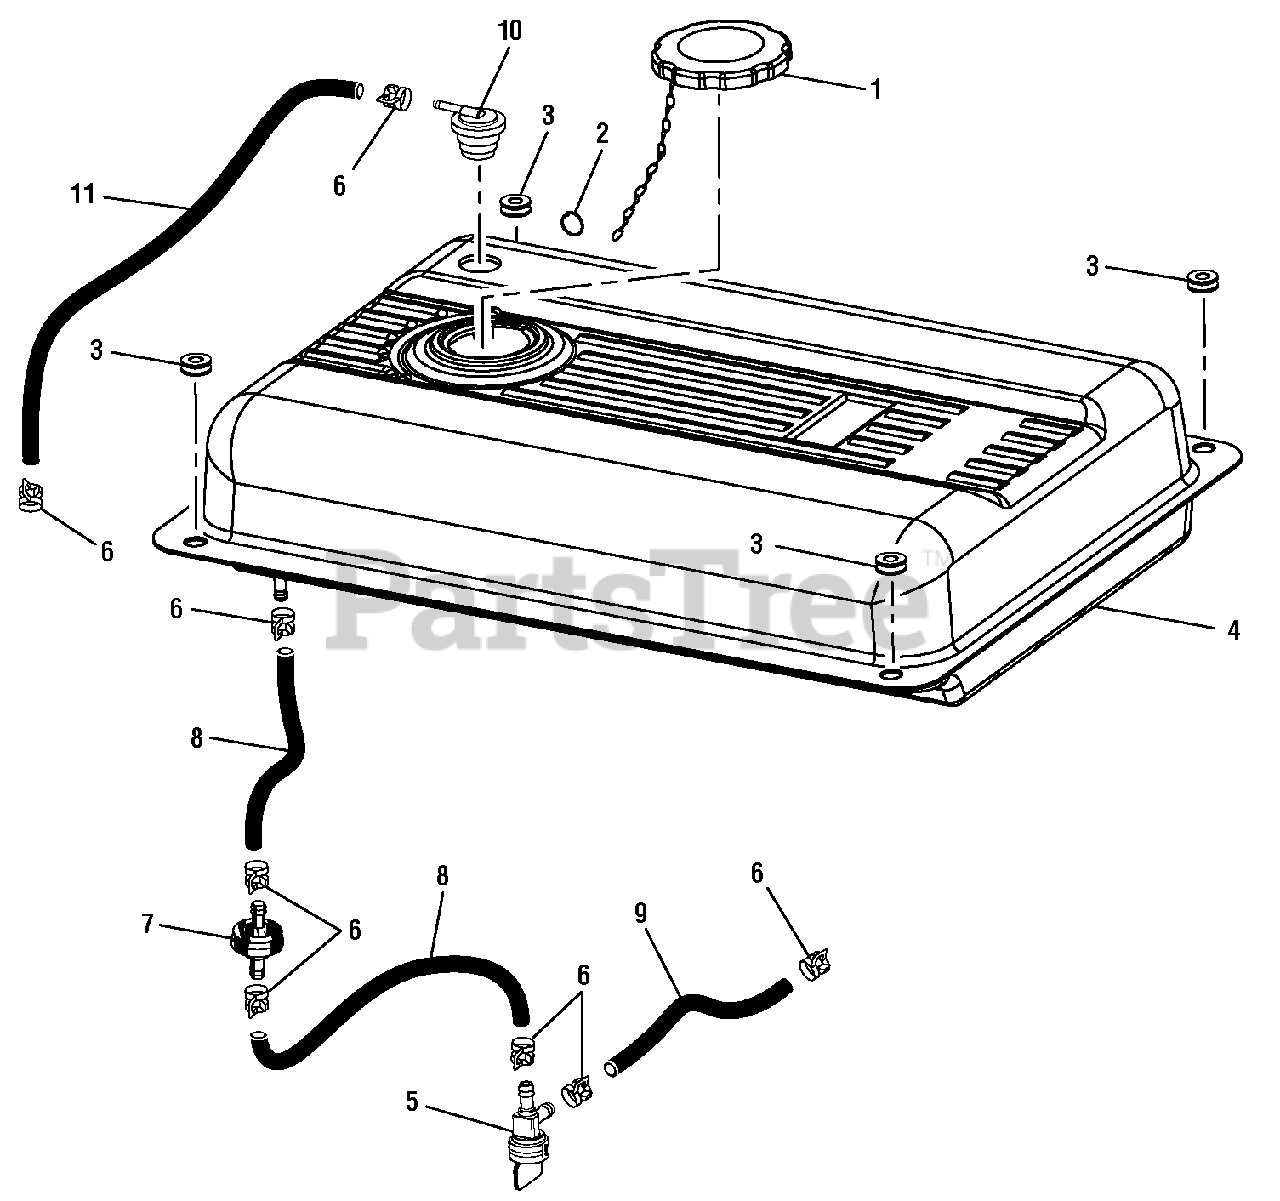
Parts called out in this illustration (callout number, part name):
1	Fuel Tank Cap
2	Ring Clip
3	Bushing w/Insert
4	Fuel Tank Assembly
5	Fuel Valve
6	Fuel Line Clamp (1/2 in.)
7	Fuel Line Filter
8	Fuel Line (1/4 in.)
9	Fuel Hose (5 mm)
10	Vapor Vent
11	Vapor Hose
